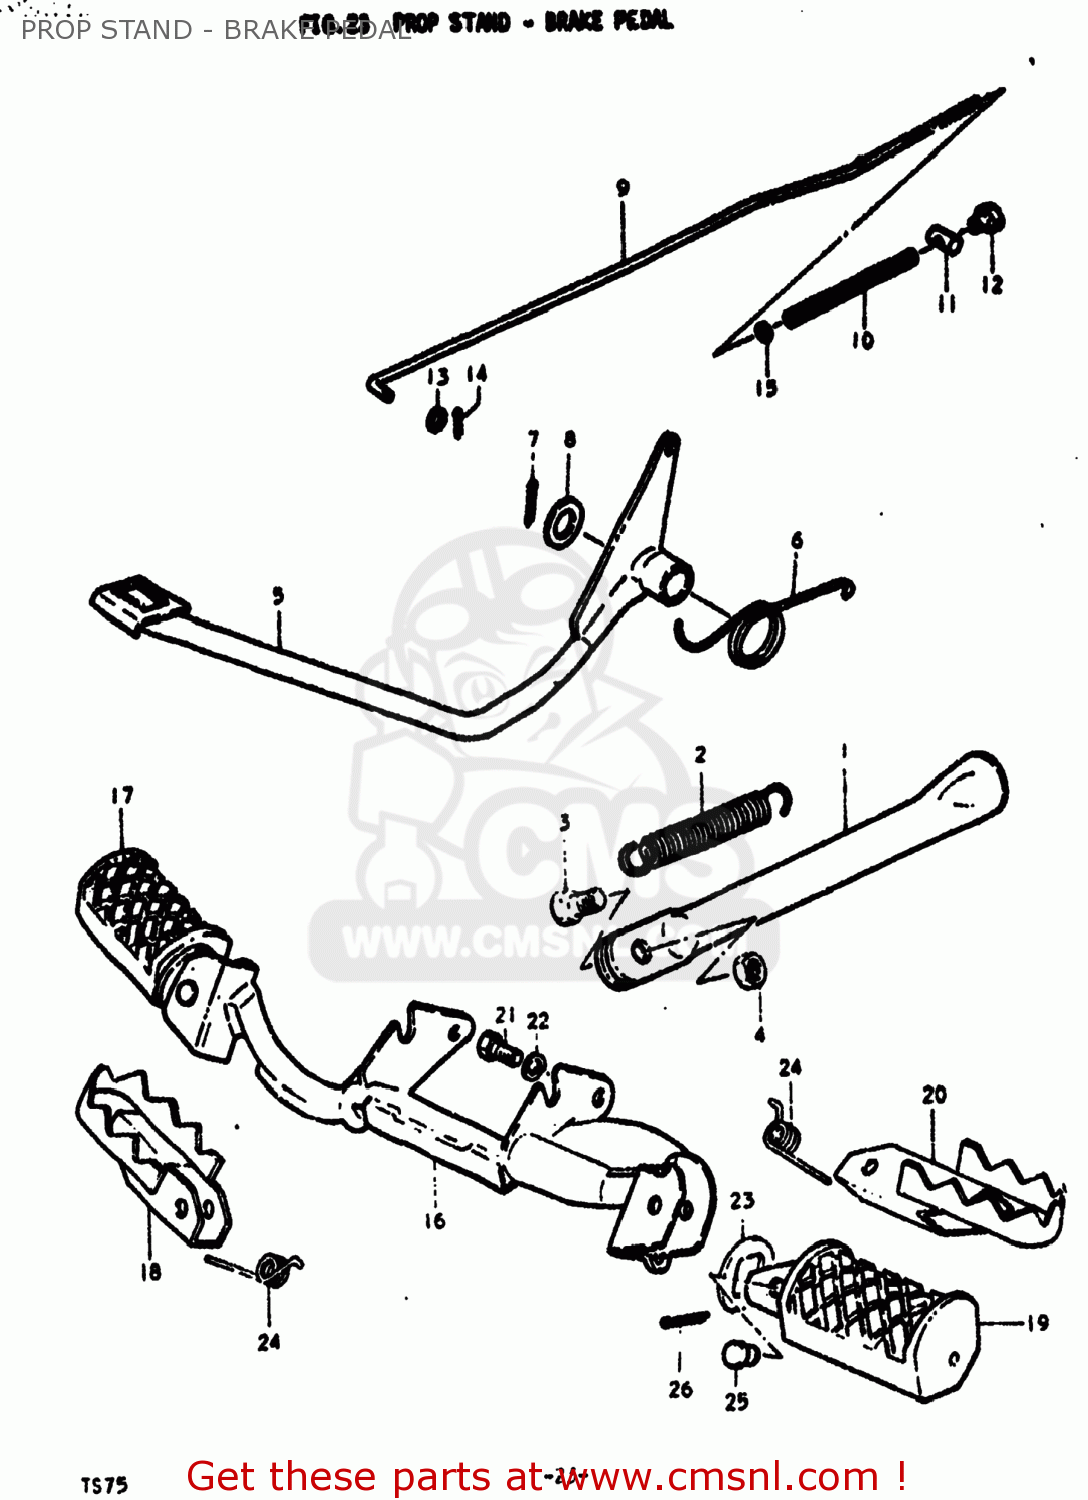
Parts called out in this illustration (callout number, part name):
1	STAND,SIDE
2	SPRING
3	BOLT
4	NUT
5	PEDAL,BRAKE
6	SPRING
7	COTTER PIN
8	WASHER(15.5X26X2.3)
9	ROD ASSEMBLY,REAR BRAKE
10	SPRING
11	PIN(11X18)
12	NUT
13	WASHER
14	PIN 20X20
15	WASHER
16	BAR,FRONT FOOTREST
17	RUBBER,FOOTREST,RIGHT
18	RUBBER,FOOTREST,RIGHT
19	RUBBER,FOOTREST,LEFT
20	RUBBER,FOOTREST,LEFT
21	BOLT
22	LOCK WASHER
23	WASHER
24	SPRING
25	PIN
26	PIN 20X20
